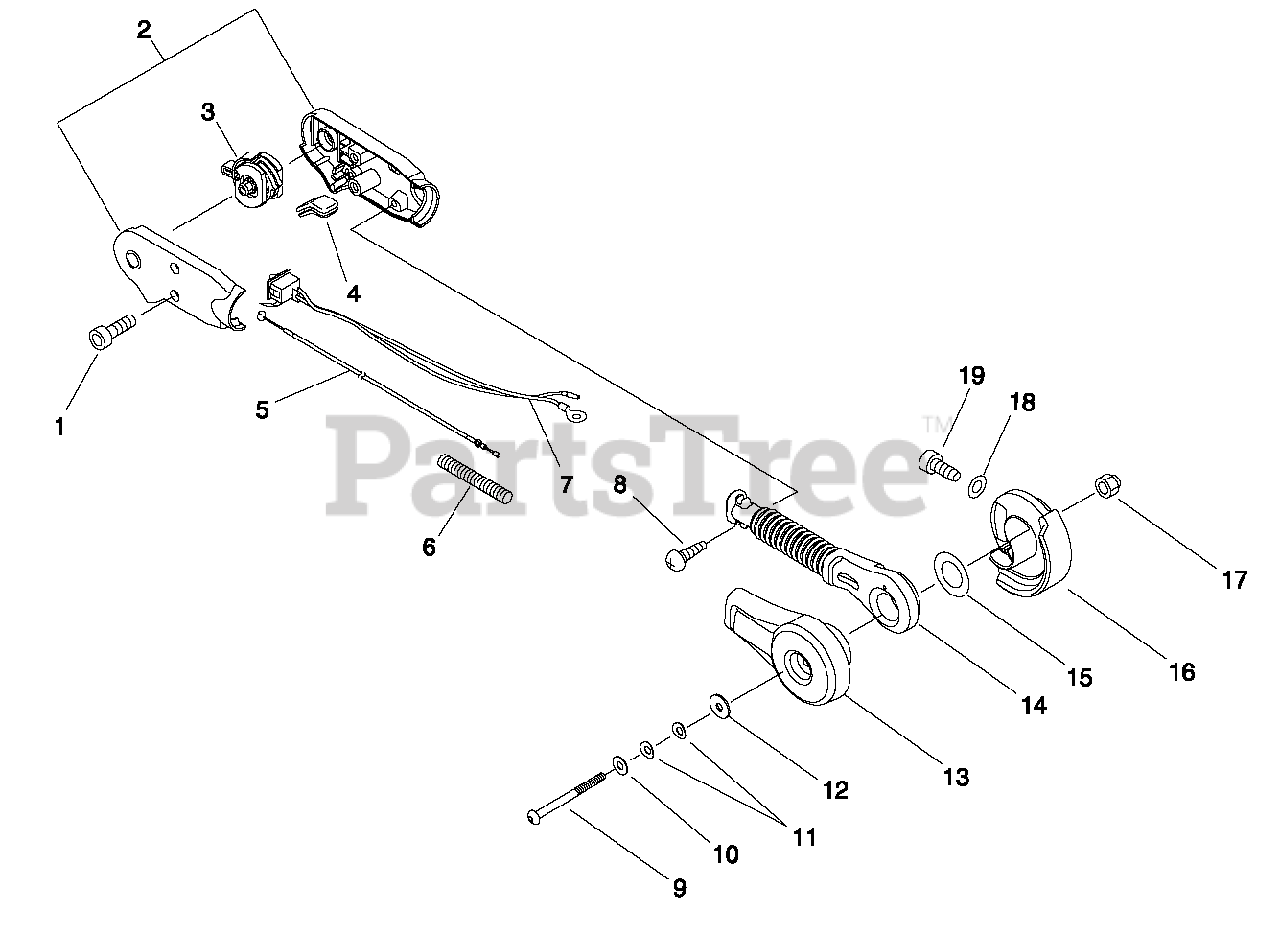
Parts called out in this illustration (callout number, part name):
1	BOLT 5×14
2	GRIP SET, THROTTLE
3	THROTTLE CONTROL ASSY
4	GROMMET
5	CABLE, THROTTLE
6	TUBE, FLEXIBLE
7	SWITCH, ON-OFF
10	WASHER 6.5×15.5×0.6
11	WASHER, FRICTION 6.6×14.3
12	WASHER 6.6×20×1.6
13	BRACKET, ARM - OUTER
14	ARM, THROTTLE CONTROL
15	WASHER 45
16	BRACKET, ARM - INNER
17	NUT, LOCK M6
18	WASHER 5.5×16×2T
19	BOLT, TAPPING 5×25
